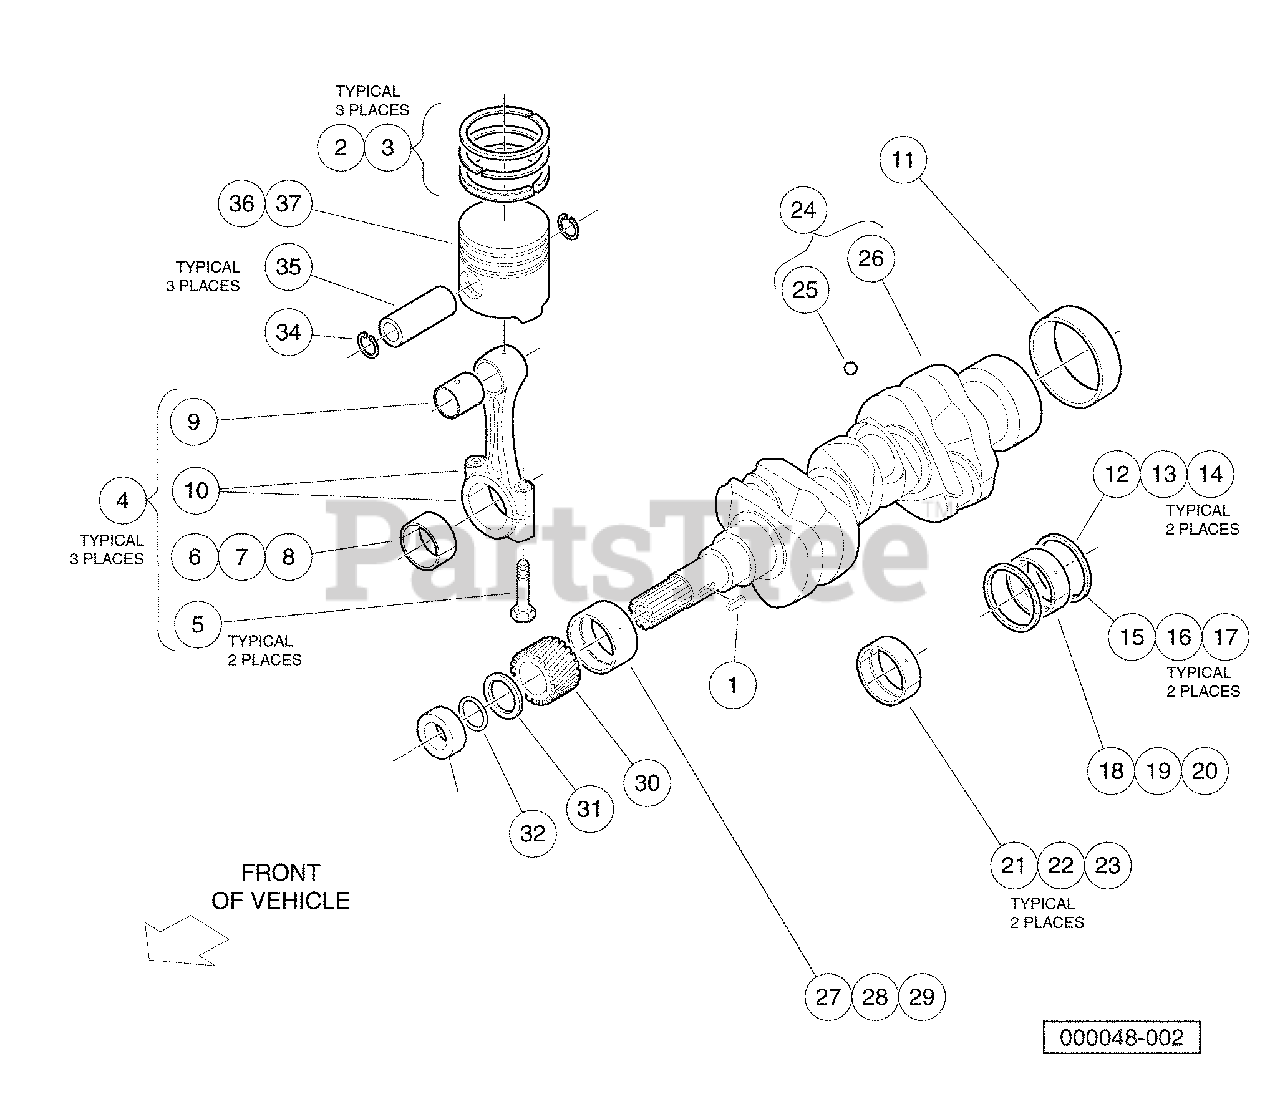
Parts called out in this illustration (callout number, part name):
1	Key, Feather, Short Camshaft
2	Assy Piston Ring, D722 Std
3	Assy Piston Ring, D722 +.025
4	Assy, Connecting Rod
5	Bolt, Connecting Rod
6	Metal, Crank, Rod, D722, Std
7	Metal, Crank, Rod, D722, .020
8	Metal, Crank, Rod, D722, .040
9	Bushing, Piston Pin, D722
10	Rod, Connecting
11	Sleeve, Crankshaft
12	Metal,crank, O Side, Std
13	Metal,crank, O Side, +.020
14	Metal,crank, O Side, +.040
15	Metal,crank, I Side, Std
16	Metal,crank, I Side, +.020
17	Metal,crank, I Side, +.040
18	Metal, Crank, Main, Rear Std
19	Metal, Crank, Main, Rear -.020
20	Metal, Crank, Main, Rear -.040
21	Metal, Crank, Main, Mid Std
22	Metal, Crank, Main, Mid +.020
23	Metal, Crank, Main, Mid +.040
24	Crankshaft
25	Ball, Crankshaft
26	Crankshaft
27	Metal, Crank, D722, Frnt, Std
28	Metal, Crank, 722, Frnt, -.020
29	Metal, Crank, 722, Frnt, -.040
30	Gear, Crank
31	Slinger, Oil
32	O Ring, 23 X 26
33	Collar, Crankshaft
34	Circlip, Piston Pin
35	Pin, Piston
36	Piston, D722, Std
37	Piston, D722, +0.25
